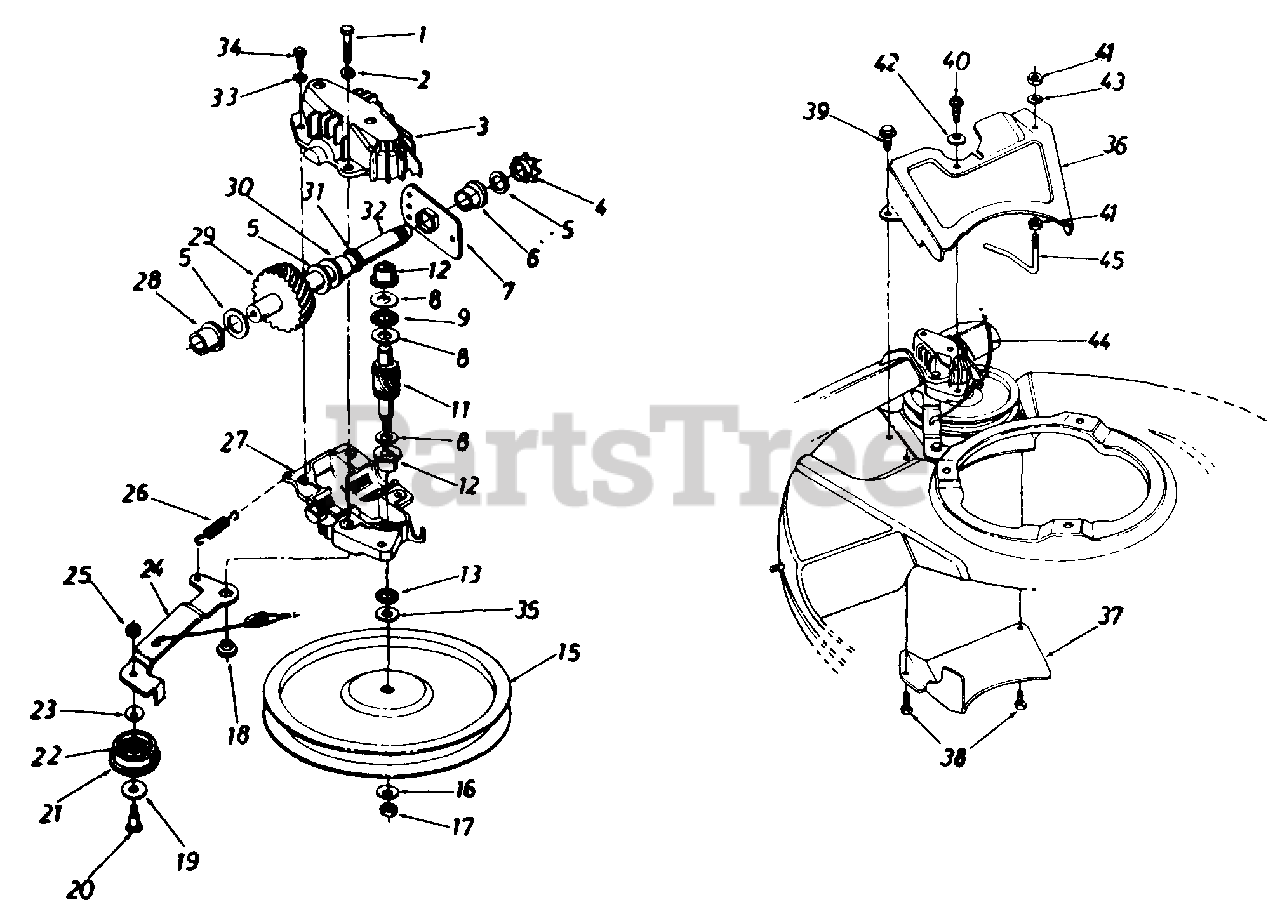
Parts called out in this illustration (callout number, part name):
1	Hex Bolt 1/4-20 x 1.25" Lg.
2	L-Wash. 1/4" I.D.
3	Upper Hsg. Half
4	#48 Sprocket 7 Tooth x 1/2 Pitch
5	Fl-Wash. 5/8" I.D. x .030
6	Hex Flange Brg. .631" I.D.
8	Thrust Wash. .382" I.D. x .70" O.D.
9	Thrust Bearing .375" I.D. x .812" O.D.
11	11 Tooth Helical Gear
12	Flange Bearing
15	Fl-Pulley 5.06" I.D.
16	Bell-Wash. .265" I.D. x .75"
17	Hex Nut 1/4-28 L.H. Thd.
18	Shld. Spacer .375" Dia. x .170
19	Fl-Wash. .390" I.D. x 1.0"
20	Shld. Bolt .375" Dia. x .40"
21	Fl-Idler Plastic 1.50" Dia.
22	Needle Brg. .375" x .31"
23	Bell-Wash. .265" I.D. x .75"
24	Idler Brk't. Ass'y.
25	Hex Patch L-Nut 1/4-28 Thd.
26	Extension Spring 1.12" Lg.
27	Lower Hsg. Half
28	Flange Bearing .56 Dia.
29	33 Tooth Helical Gear
30	Flange Bearing .629 Dia.
31	Oil Seal .625 Dia.
32	Gear Sprocket Shaft
33	L-Wash. #10 I.D.
34	Hex B-Tap Scr. #10 x .62"
35	Hex Washer .26" x .88"
39	Hex AB-Tap Scr. 1/4 x .50" Lg.
40	Hex B-Tap Scr. 1/4 x .62" Lg.
41	Hex Nut 1/4-20 Thd.
42	Bell-Wash. .265" I.D. x .75"
43	L-Wash. 1/4" I.D.
44	S.P. Cable - 48" Lg.
45	S.P. Belt Guard
